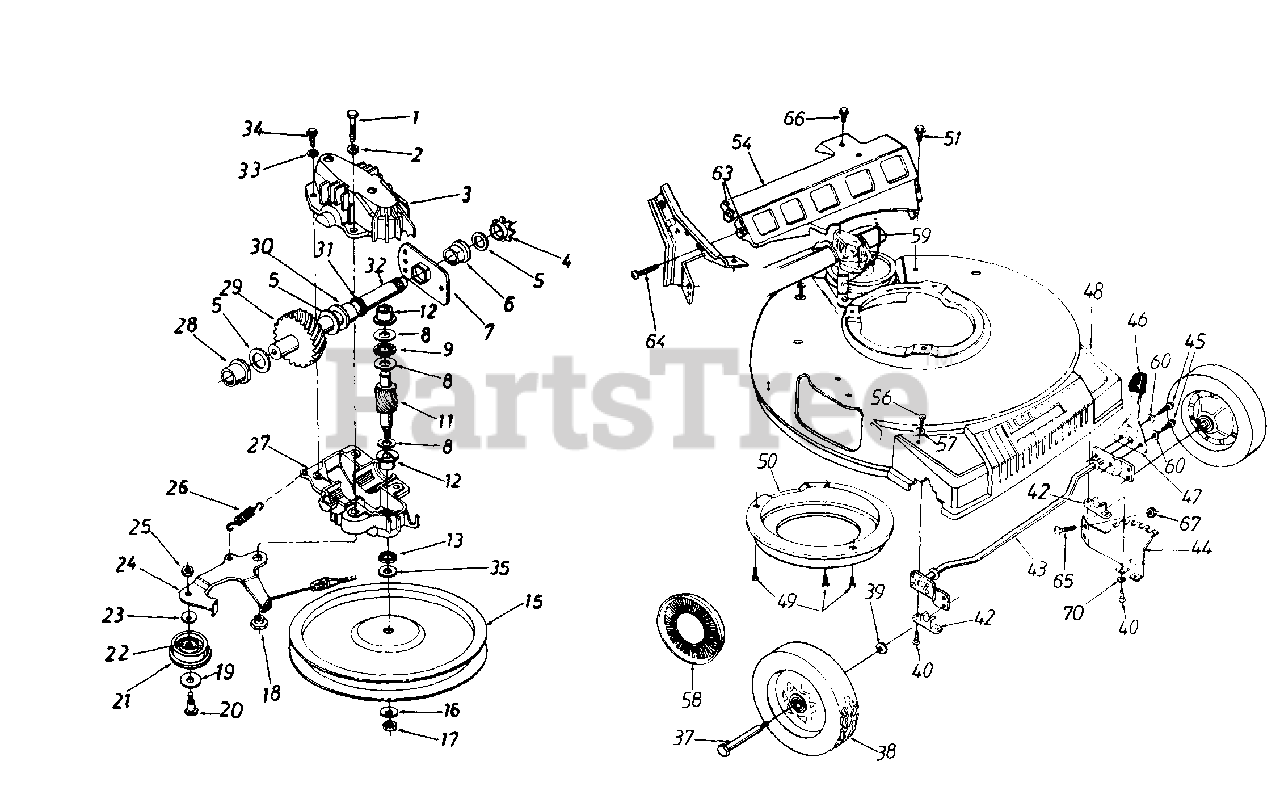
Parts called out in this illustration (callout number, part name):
1	Hex Patch Bolt 1/4-20 x 1.25"
2	L-Wash. 1/4" I.D.
3	Upper Hsg. Half
4	#48 Sprocket 7 T x 1/2 Pitch
5	Fl-Wash. 5/8" I.D. x .030
6	Hex Flange Brg..631" I.D.
8	Thrust Wash..382" I.D. x .70" O.D.
9	Thrust Bearing .375" I.D. x .812" O.D.
11	11 Tooth Pinion Shaft
12	Flange Bearing
13	Oil Seal
15	Fl-Pulley 5.06" O.D.
16	Bell-Wash..265" I.D. x .75"
17	Hex L-Nut 1/4-28 L.H. Thd.
18	Shld. Spacer .375" Dia. x .170
19	Fl-Wash..390" I.D. x 1.0"
20	Shld. Bolt .375" Dia. x .40"
21	Fl-Idler Plastic 1.50" Dia.
22	Needle Brg..375" x .31
24	Idler Brk't. Ass'y.
25	Hex Patch L-Nut 1/4-28 Thd.
26	Extension Spring 1.12" Lg.
27	Lower Hsg. Half
28	Flange Bearing .566 Dia.
29	33 Tooth Helical Gear f
30	Flange Bearing .629 Dia.
31	Oil Seal .625 Dia.
32	Gear Sprocket Shaft
33	L-Wash. #10 I.D.
34	Hex B-Tap Scr. 010 x .62"
35	Hex Washer .26" x .88"
37	Front Axle Bolt
38	Wheel Ass'y. Comp. 8 x 2"
39	Bell-Wash..380" I.D. x .88
40	Hex Wash. Hd. Scr. 1/4 x 1" Lg.
42	Block Bushing
45	Hex TT-Tap Scr. 1/4-20 x .38"
46	Knob
47	Spring Lever
48	Plastic Front End
49	Hex B-Tap Scr. 1/4" x .38"
57	Bell-Wash..345" I.D. x .88"
58	Hub Cap
59	S.P. Cable
60	External L-Wash. 1/4" I.D.
63	Speed Nut 410-24 Thd.
64	Hex Tap Scr. #10-16 x .5" Lg.
65	Carr. Bolt 1/4-20 x .5" Lg.
66	Hex B-Tap Scr. 5/16-18 x .5"
67	Hex Flange L-Nut 1/4-20 Thd.
70	L-Wash. 1/4" I.D.
